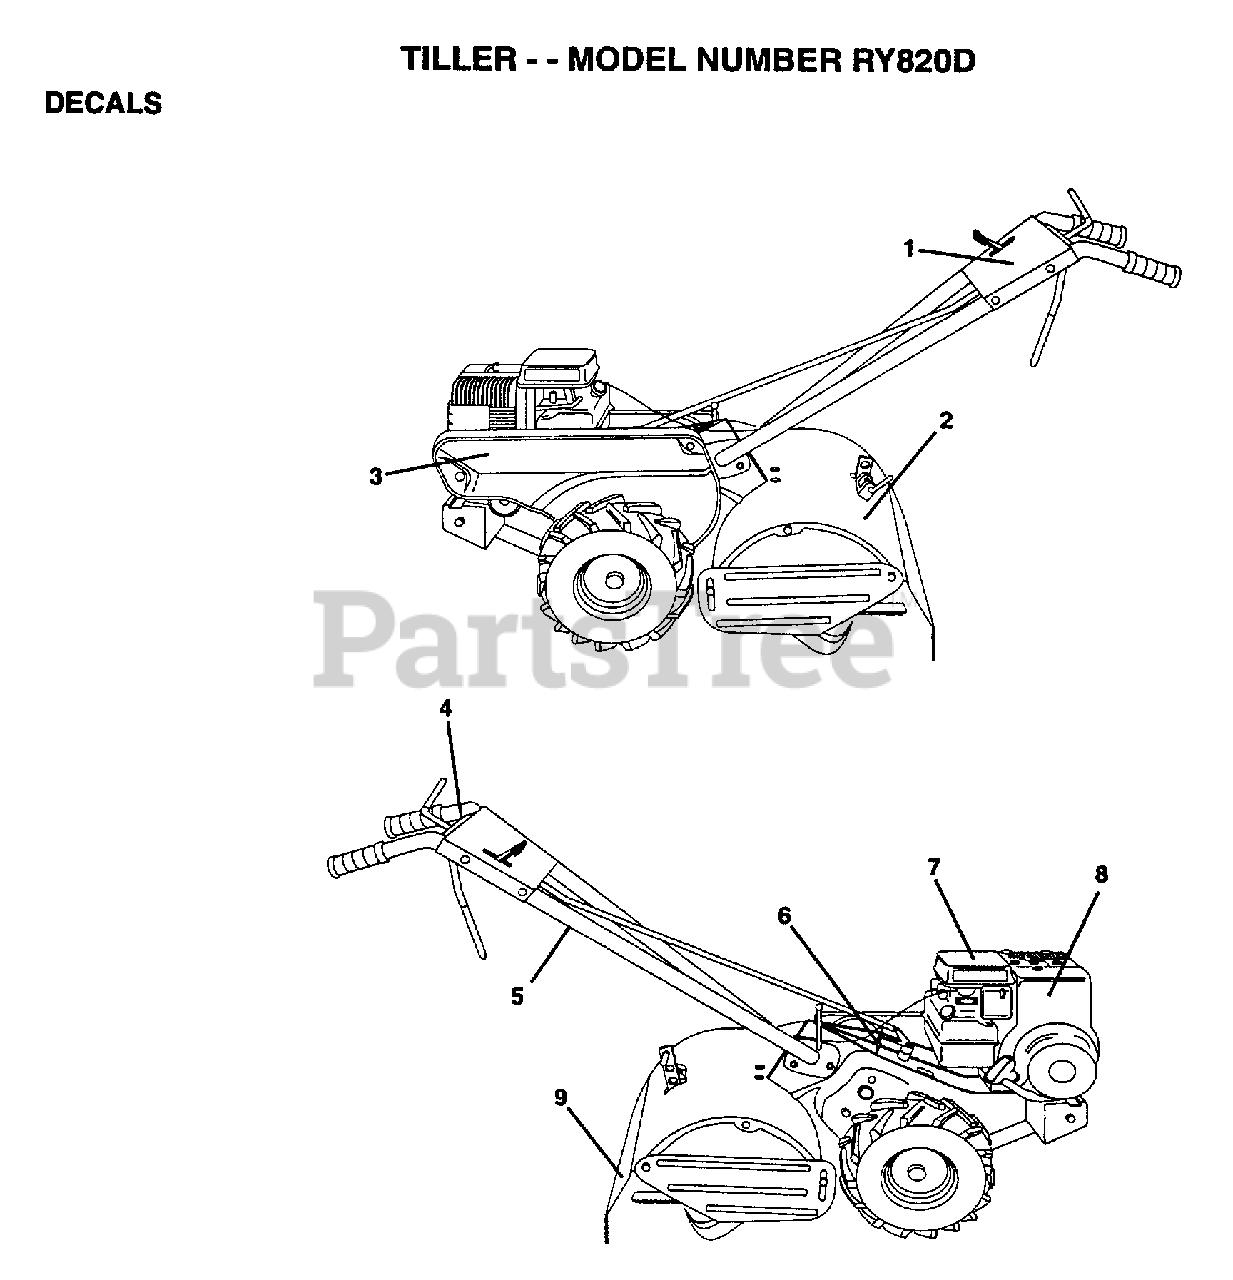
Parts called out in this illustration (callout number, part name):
3	DECAL, LOGO
5	DECAL TI
7	DECAL TI
8	DECAL, BRIGGS & STRATTON
